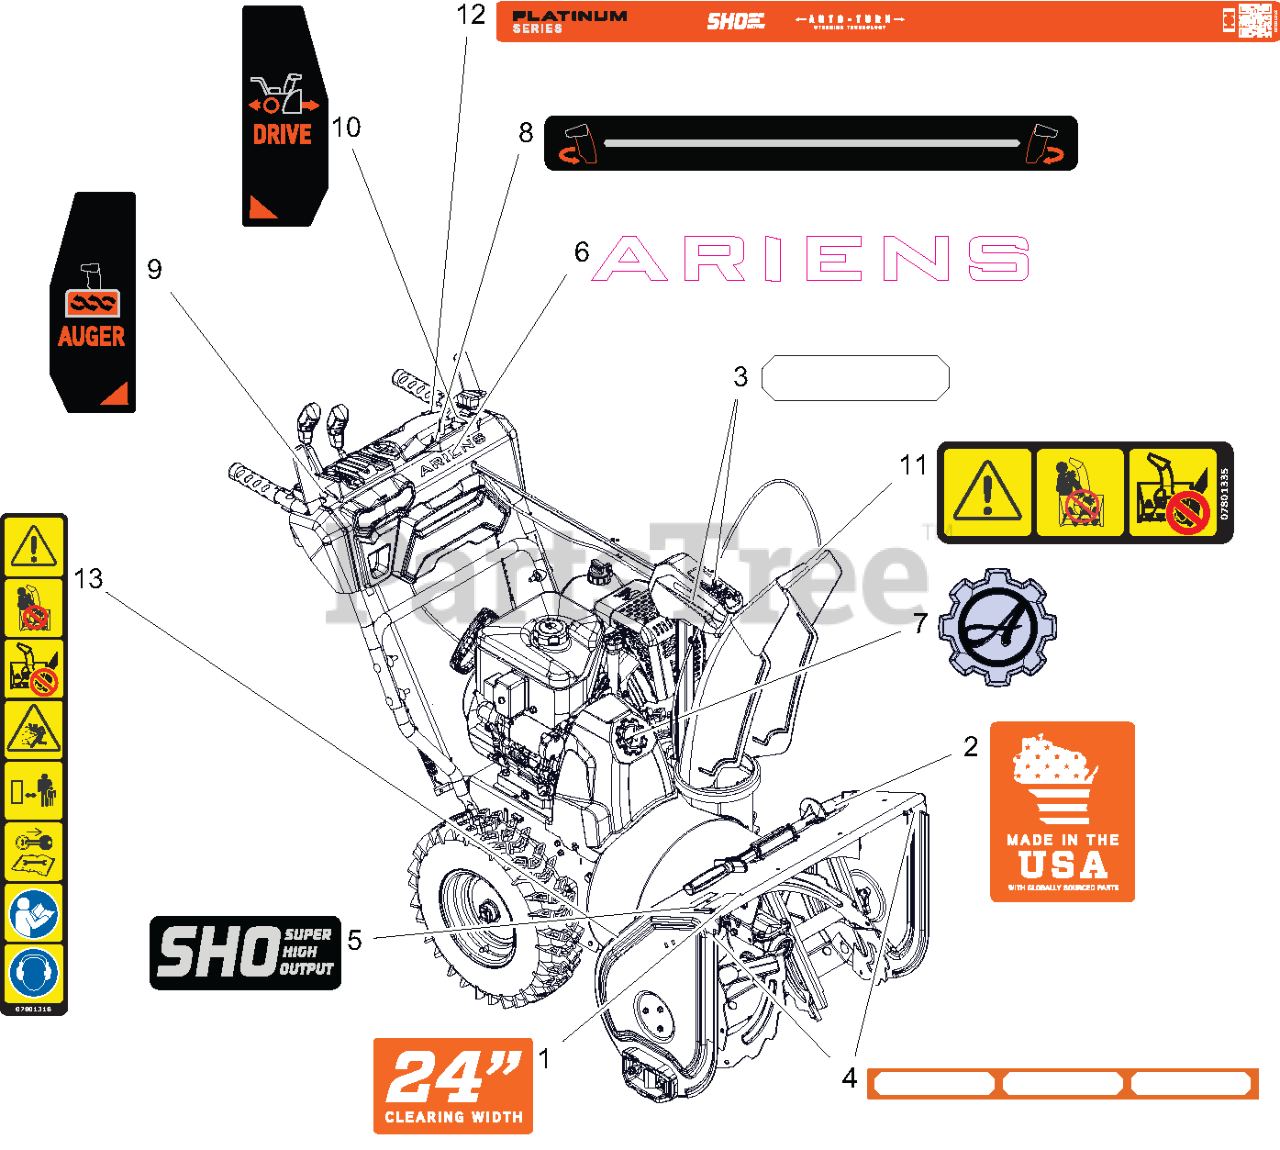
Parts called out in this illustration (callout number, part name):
1	DECAL- CLEARING - 24
2	DECAL- MADE IN USA
3	DECAL,REFLECTIVE,GEAR COVER
4	DECAL,REFLECTIVE,HOUSING
5	DECAL, SHO
6	DECAL- ARIENS - 7.46"
7	DECAL, ARIENS - GEAR BADGE
8	DECAL- CHUTE ROTATION
9	DECAL- CONTROL - AUGER
10	DECAL- CONTROL - DRIVE WHEEL
11	DECAL- DANGER
12	DECAL- DASH - PLT
13	DECAL- SAFETY - DANGER
